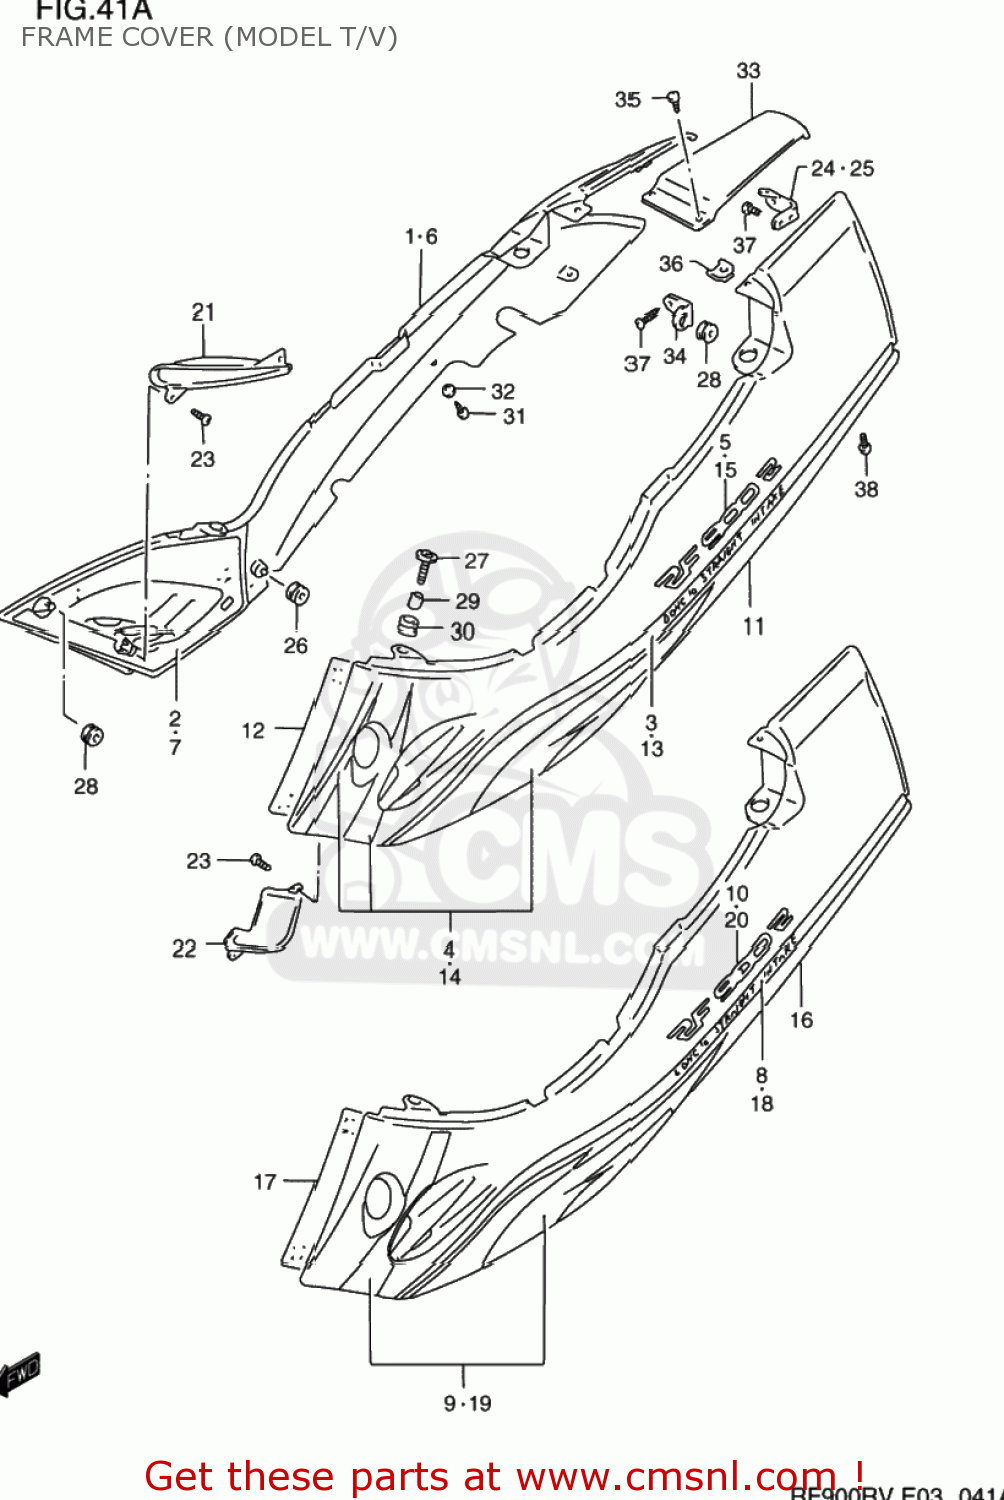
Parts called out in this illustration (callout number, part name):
1	COVER ASSY,FRAME,R(GRAY)
2	SHIELD,FRAME COVER HEAT
3	TAPE SET,FRAME COVER S
4	TAPE SET,FRAME COVER,R
5	EMBLEM,FRAME COVER
6	COVER ASSY,FRAME,R(BLACK)
7	SHIELD,FRAME COVER HEAT
8	TAPE SET,FRAME COVER S
9	TAPE SET,FRAME COVER,R
10	EMBLEM,FRAME COVER
11	COVER,FRAME,LEFT (GRAY)
12	SHIELD,FRAME COVER HEAT,L
13	TAPE SET,FRAME COVER S
14	TAPE SET,FRAME COVER,L
15	EMBLEM,FRAME COVER
16	COVER ASSY,FRAME,L(BLACK)
17	SHIELD,FRAME COVER HEAT,L
18	TAPE SET,FRAME COVER STRIPE,L
19	TAPE SET,FRAME COVER,L
20	EMBLEM,FRAME COVER
21	COVER,INNER,RIGHT
22	COVER,INNER,L
23	SCREW
24	BRACKET,FRAME COVER,R
25	BRACKET,FRAME COVER,L
26	CUSHION
27	BOLT(6X25)
28	CUSHION,FRAME COVER FR
29	SPACER(6.5X9X11)
30	CUSHION
31	SCREW 5X12
32	WASHER(5.2X14X1.5)
33	COVER,FRAME CTR
34	BRACKET,RR COMBINATION LAMP
35	SCREW 5X12
36	NUT
37	SCREW
38	SCREW
